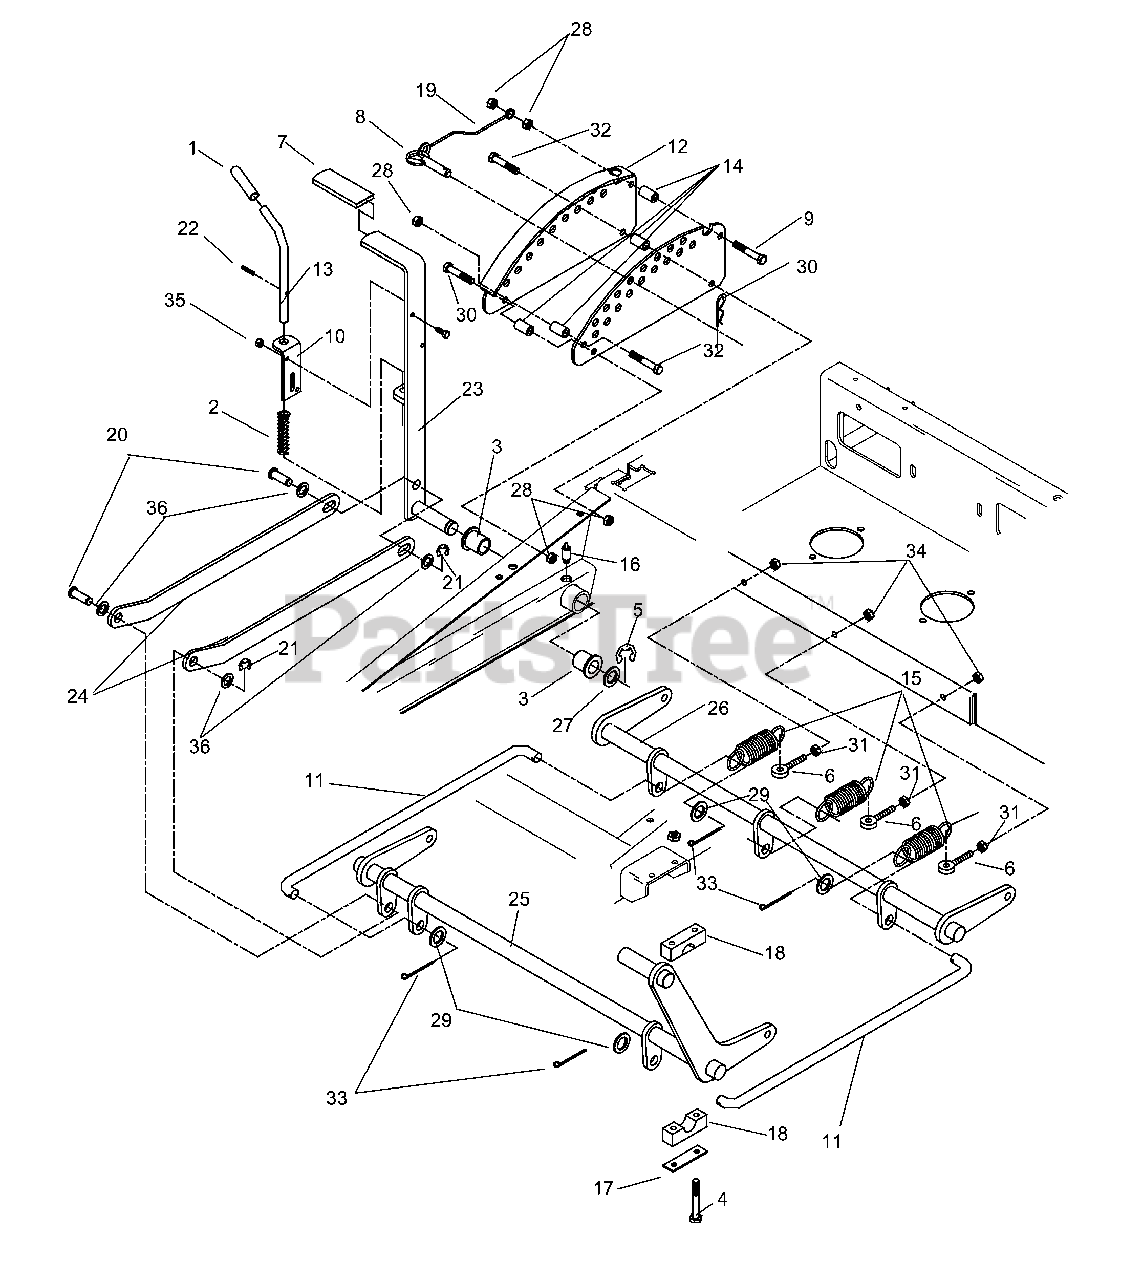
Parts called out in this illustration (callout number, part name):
3	BUSHING, FLANGED
4	HCS 5/16C X 2-3/4
5	E-RING 7/8
6	EYEBOLT, RH
8	HITCH PIN
9	SCREW 3/8C X 2 3/4 HEX CAP
10	PIN MT, UPPER
11	CONNECTING LINK
12	ADJ. PLATE WLDMNT
14	DECK LIFT SPACER
15	DECK LIFT SPRING
16	GREASE ZERK LONG
17	REINFORCEMENT BAR
18	PILLOW BLOCK
19	LANYARD
20	CLEVIS PIN
21	E-RING 5/8
23	LIFT LEVER WELDMENT
24	STRAP, LIFT
25	SHAFT, LIFT, FRONT
26	SHAFT, LIFT, REAR
27	BSHG .875 X 1.375 X .074 ZD
28	NUT 3/8-16 NYLOC
29	WASHER 5/8 FLAT
30	HAIRPIN #4
31	NUT 5/16C WHIZ
32	HCS 3/8C X 2 1/4
33	COTTER PIN
34	NUT 5/16 NYLOC
35	NUT 1/4C CENTER LOCK
36	BUSHING
